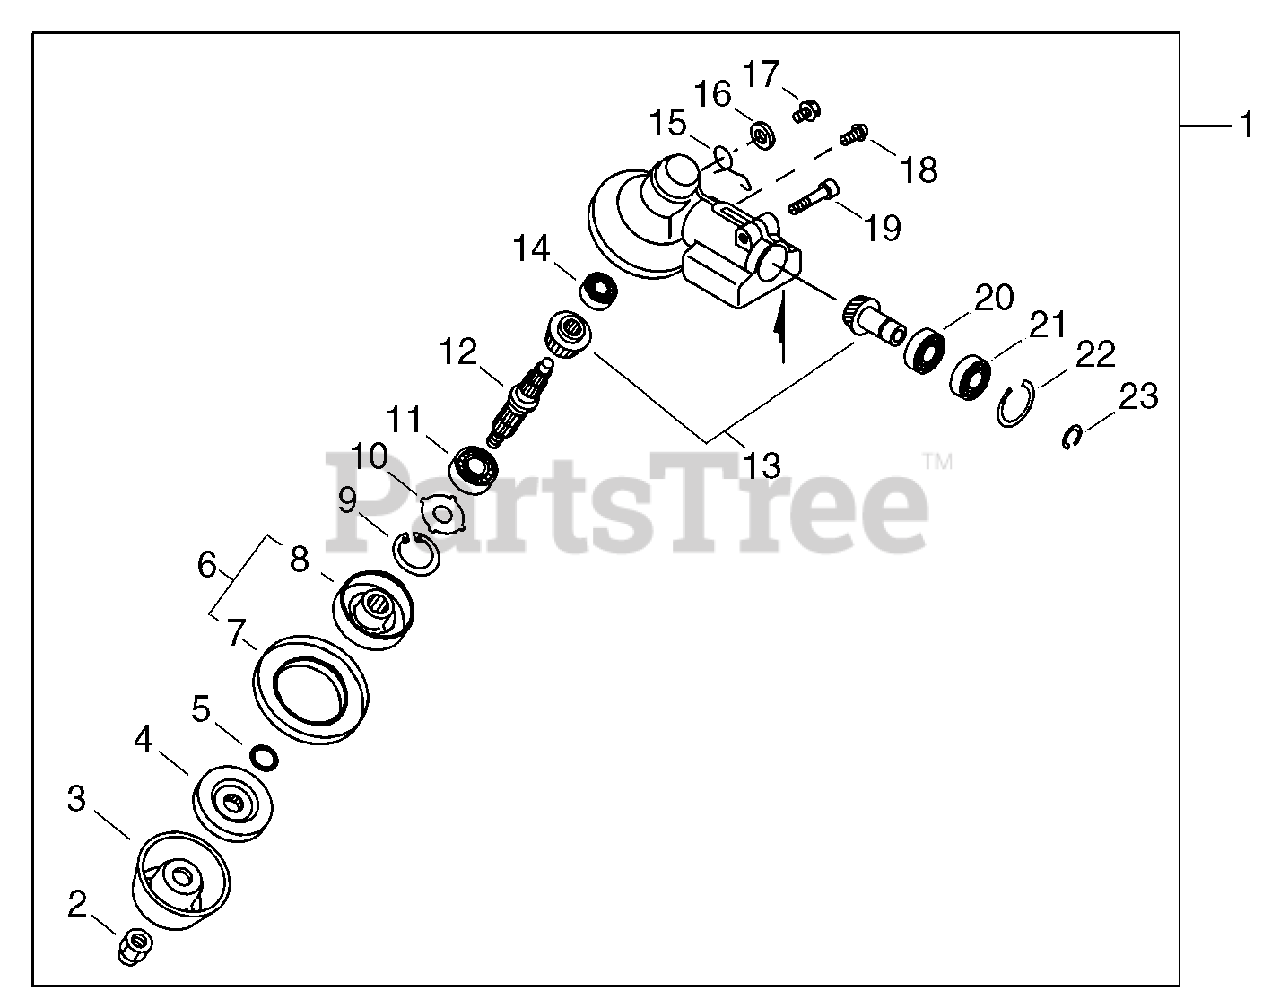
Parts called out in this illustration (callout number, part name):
1	GEAR CASE ASSY
2	NUT - 10
4	ADAPTOR, BLADE - LOWER
5	O-RING - 12
6	BLADE ADAPTER KIT
7	RETAINER, BLADE
8	ADAPTOR, BLADE - UPPER
9	RING, RETAINING - 32
11	BEARING, BALL - 6201
12	GEAR - SHAFT
13	GEAR SET
14	BEARING, BALL - 626
16	WASHER - 8
17	BOLT - 8X8
18	SCREW - 5X10
19	SCREW - 6X25
20	BEARING, BALL - 6900
21	BEARING, BALL - 6900Z
22	RING, RETAINING - 22
23	RING, RETAINING - 10
